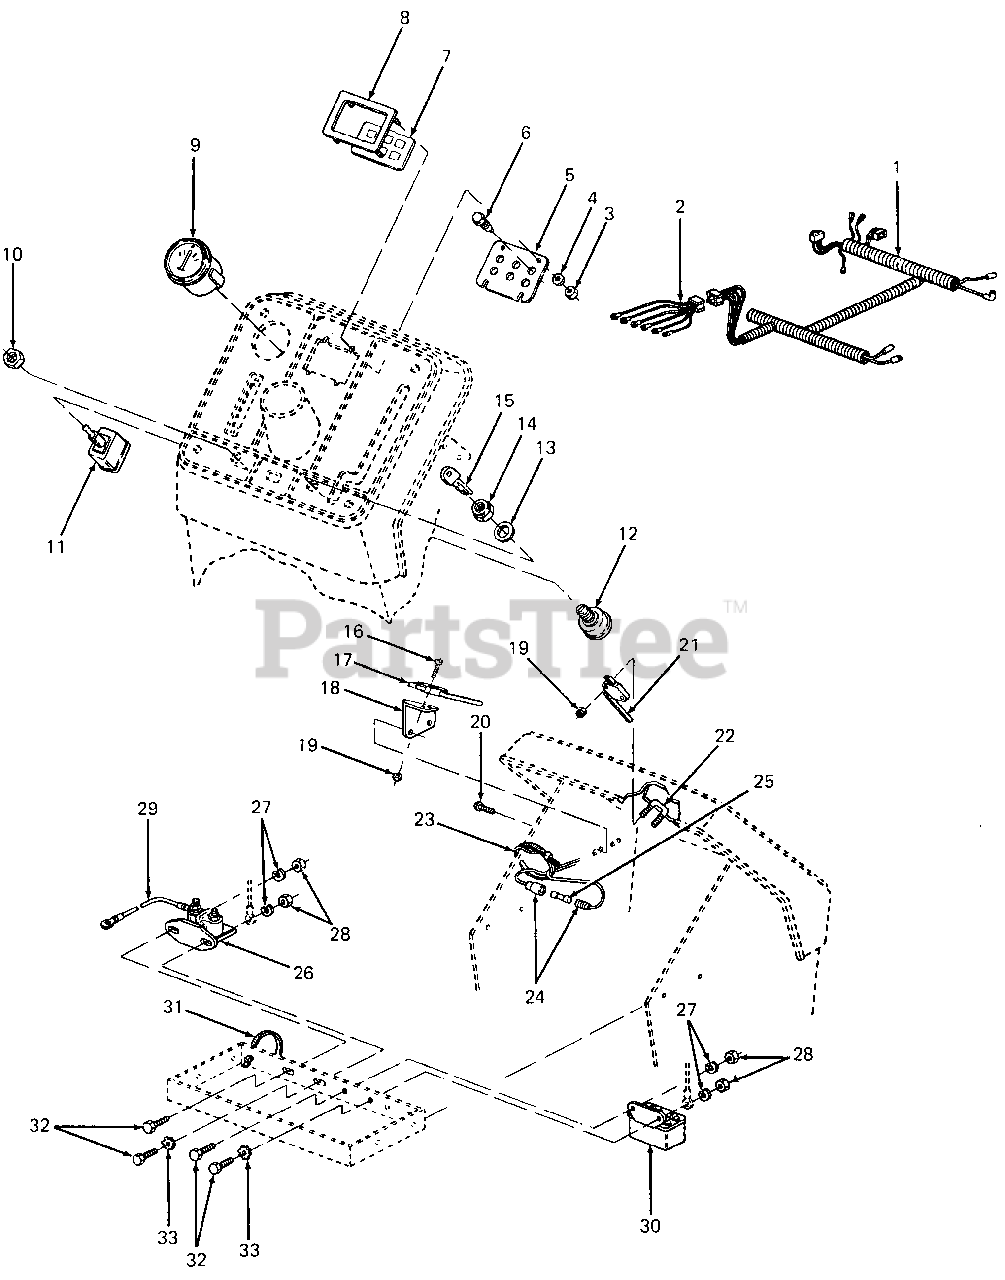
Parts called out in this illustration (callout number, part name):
1	Harness, Wire
2	Harness, Indicator Wire
3	Nut, Self-Threading Pal
4	Washer, Rubber, .18 X .50 X .06 Thk
5	Plate, Indicator
6	Lamp, Indicator
7	Label, Indicator
8	Bezel, Light
9	Ammeter
10	Nut, Hex, 1/2-27 X .100 Thk
11	Switch, PTO
12	Switch, Ignition Key
13	Washer, Flat
14	Nut, Ignition Switch
15	Key, Ignition (Set of 2)
16	Screw, Hex Hd Mach, #4-40 X .75 Lg
17	Switch, Micro
18	Plate, Switch
19	Nut, Hex Insert Lock, #4-40
20	Screw, Hex AB Tapp, 1/4 X .62 Lg
21	Switch, Micro
22	Screw, Switch
23	Tie, Cable
24	Fuse Holder
25	Fuse, 20 Amp Slo-Blo
26	Solenoid
27	Washer, Lock, 1/4
28	Nut, Hex, 1/4-20 GR5
29	Cable, Positive Battery, Red
30	Relay
31	Tie, Cable
32	Screw, Hex Cap, 1/4-20 X .62 Lg GR5
33	Washer, Int. Ext. Lock, 1/4 X .75 OD
